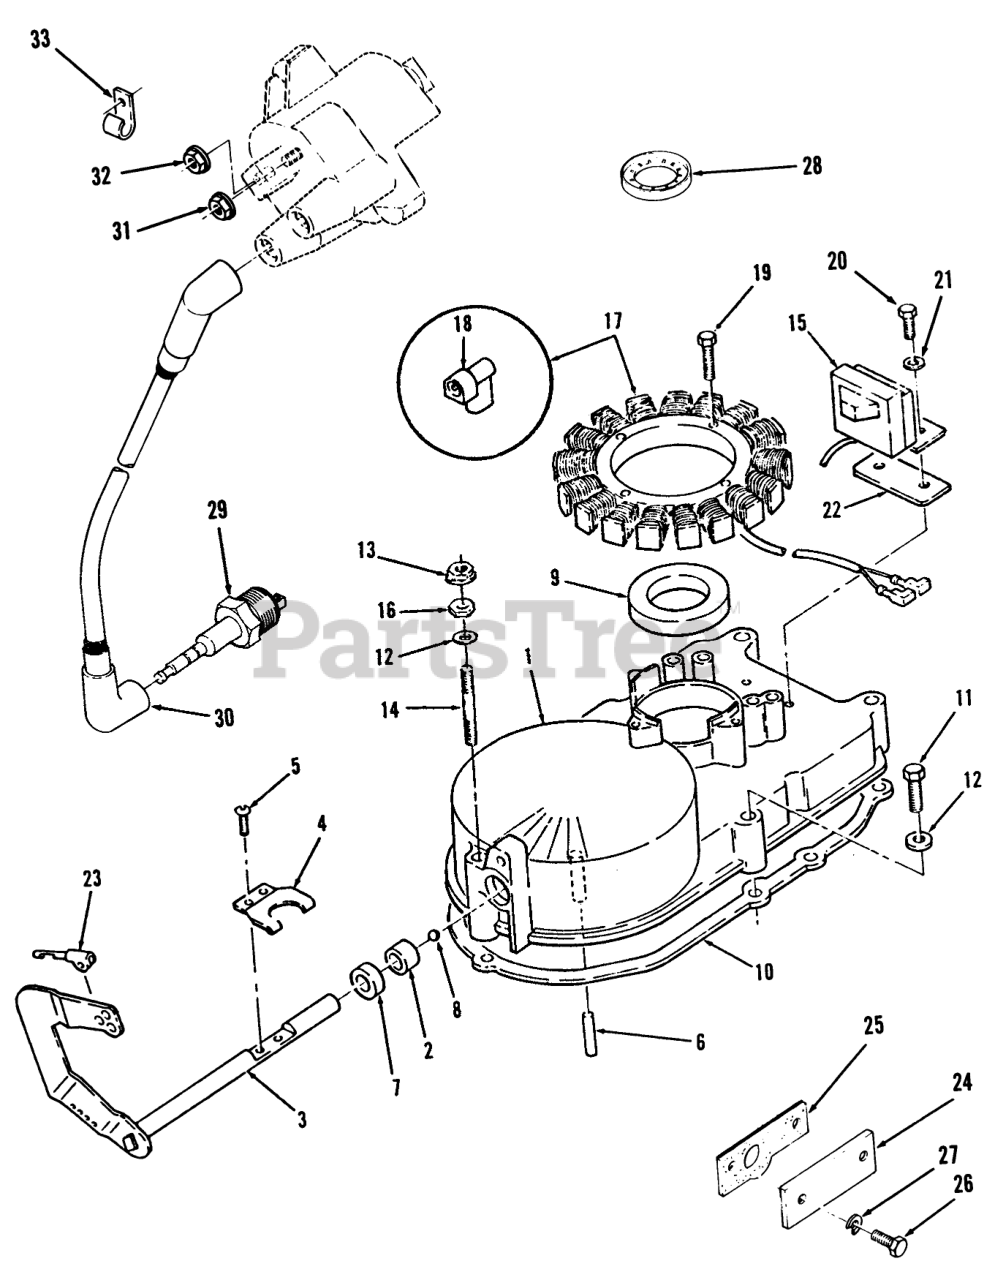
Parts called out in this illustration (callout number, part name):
1	Gearcase Kit (Includes Item 2 thru 9)
2	Bearing
3	GOVERNOR-SHAFT & ARM
4	Yoke
5	Screw
6	Washer
7	Oil Seal
8	Bearing
9	Oil Seal
10	Gasket
11	HEX-HEAD CAP SCREW
12	Washer
13	Nut
14	Stud
15	Control-Ignition
16	Nut
17	Stator w/Terminals
18	RECEPTACLE TERMINAL
19	Bolt
20	Bolt
21	Lockwasher
22	Insulator
23	Retaining Clip
24	Plate
25	Gasket
26	Bolt
27	Washer
28	Rotor
29	Plug-Spark
30	Wire-Plug
31	Nut
32	Nut
33	Clip
